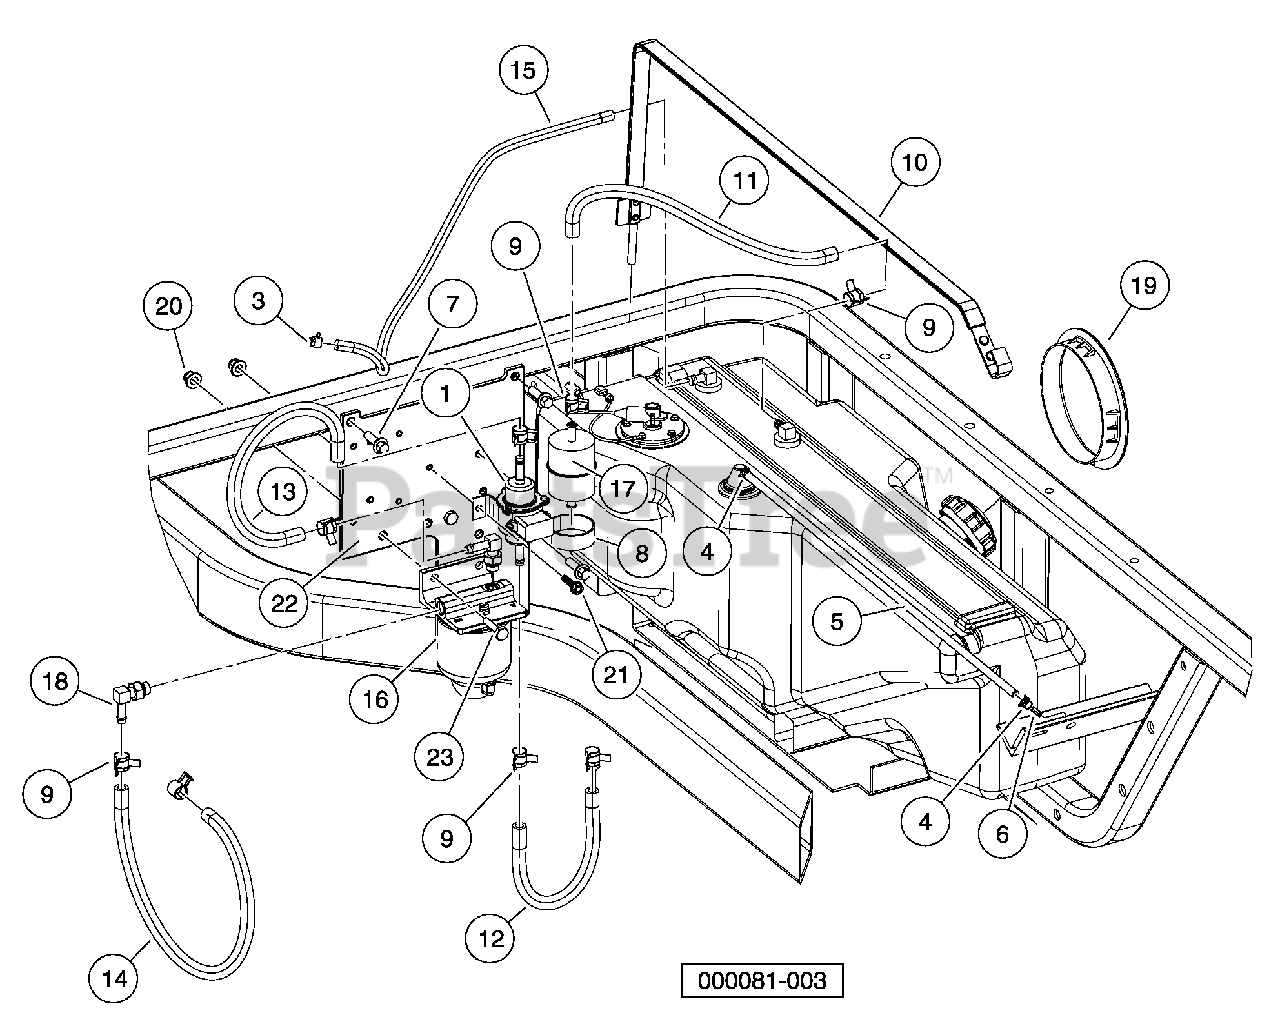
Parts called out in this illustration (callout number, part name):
1	Pump, Diesel Fuel Electric
2	Asm, Fuel System, Kubota
3	Clamp, Green Hose
4	Clamp, 0.301 ID Hose
5	Hose, Fuel, Vent, 22" Long
7	Screw, M8X1.25X30, Hex
8	P-Clamp, Insulated 1.75 In
9	Clamp, Hose, Ctb 14mm
10	Strap, Tank, Fuel
11	Hose, Tank To Prefilter Diesel
12	Hose, Fuel Prefilter To Pump
13	Hose, Fuel Pump To Filter
14	Hose, Fuel Filter To Eng
15	Hose, Fuel Return
16	Filter Assy, Fuel
17	Filter, Fuel
18	Adapter, 90, 5/16 Tube
19	Bezel, Fuel Fill
20	Lock Nut, Flg M8 X 1.25 Nylon
21	Screw, M6 X 1 X 25 Thd Form
22	Plate, Fuel/Oil System
23	Bolt, M8 X 1.25 X 30
